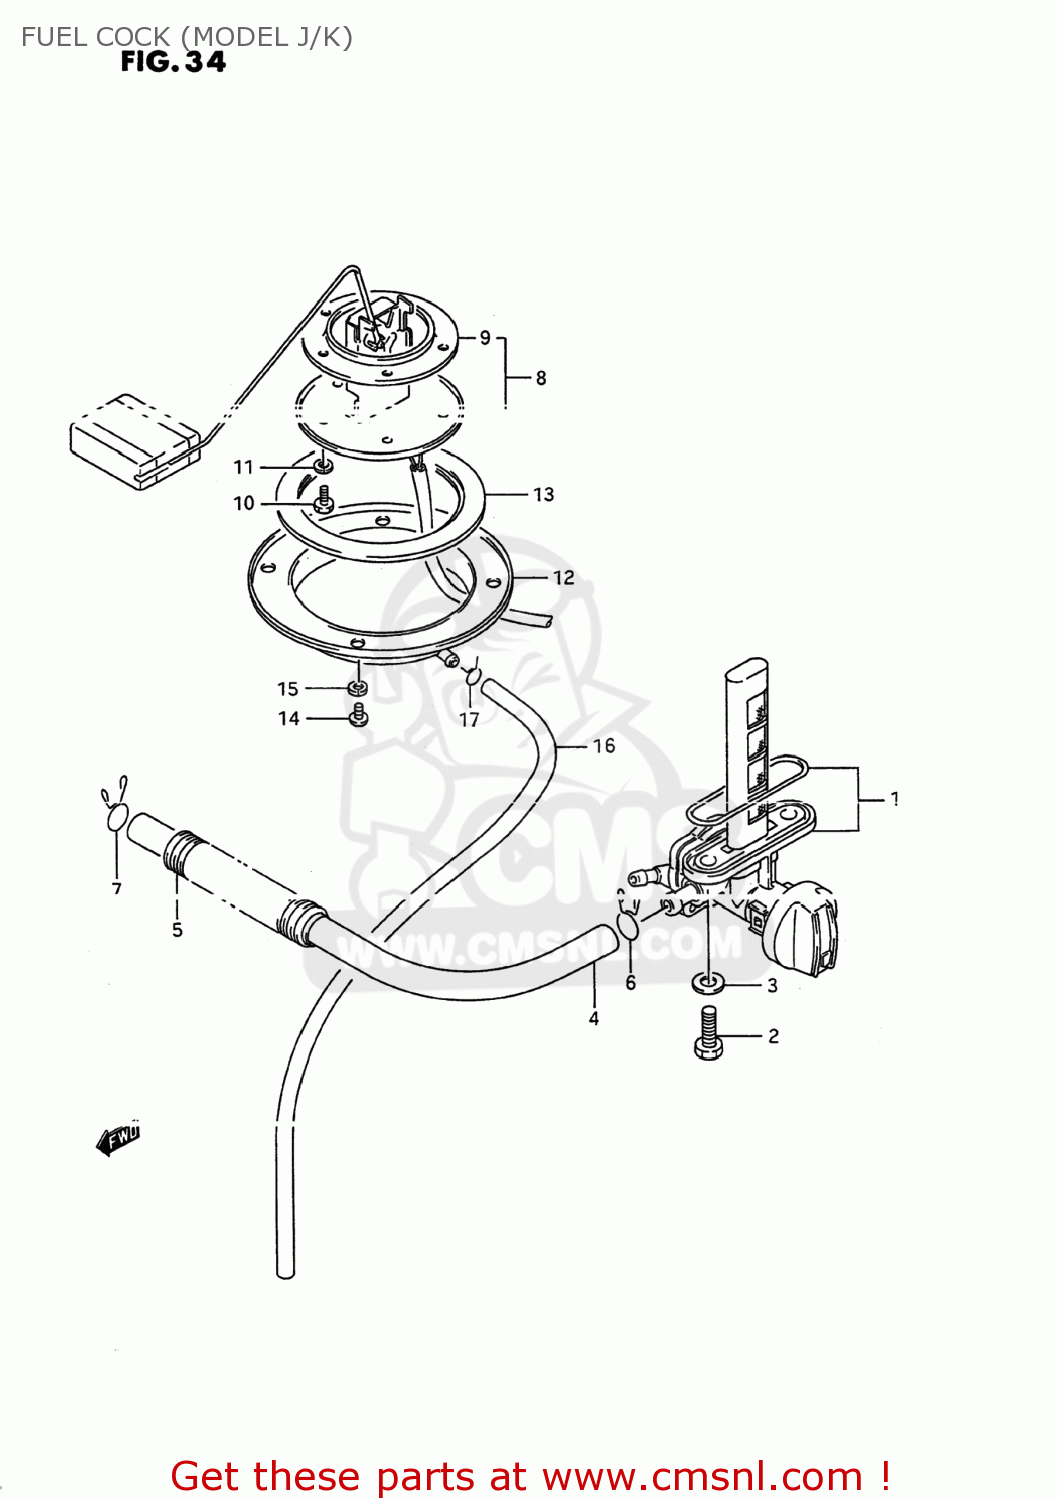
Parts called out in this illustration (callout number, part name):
1	COCK ASSY,FUEL
2	BOLT(6X20)
3	GASKET(5.8X13X1.2) (NAS)
4	HOSE (7X12X600)
5	TUBE,FUEL HOSE
6	CLAMP
7	CLIP
8	GAUGE ASSY,FUEL LEVEL SENDER
9	GASKET,FUEL LEVEL GAUGE (NAS)
10	BOLT
11	LOCK,WASHER
12	PLATE,FUEL DRAIN
13	GASKET,FUEL DRAIN PLATE (NAS)
14	SCREW
15	LOCK,WASHER
16	HOSE(5X8.2X2000)
17	CLIP
